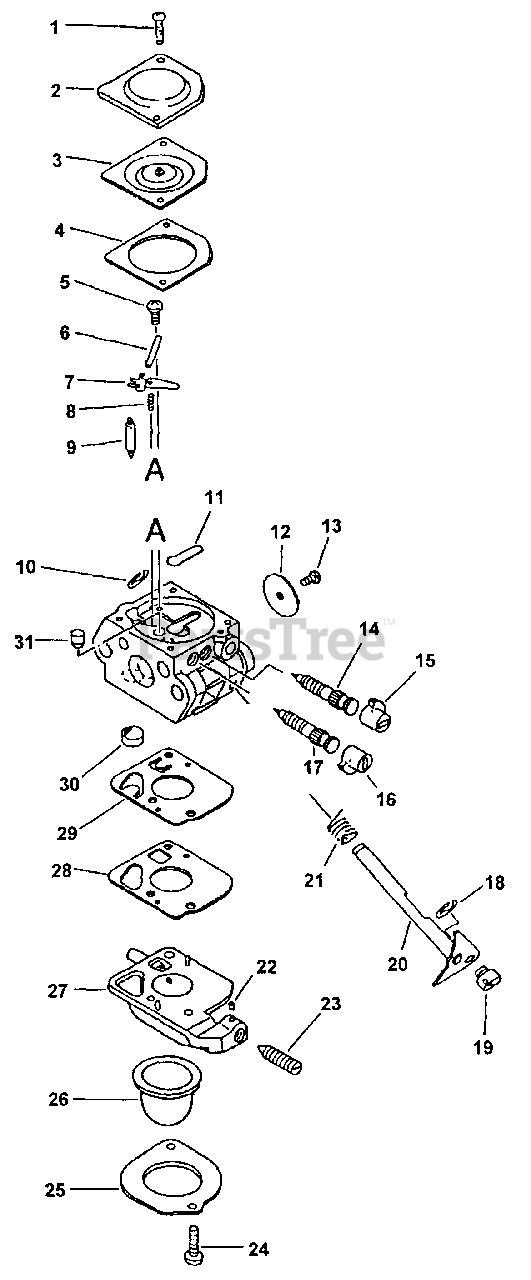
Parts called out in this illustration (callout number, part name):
2	COVER, METERING
3	DIAPHRAGM, METERING
4	GASKET, METERING
5	SCREW, METERING LEVER PIN
6	PIN, METERING LEVER
7	LEVER, METERING
8	SPRING, METERING LEVER
9	VALVE, NEEDLE
10	RING, RETAINING
11	PLUG, WELCH
12	VALVE, THROTTLE
14	NEEDLE - LOW SPEED
15	CAP, LIMITER
16	CAP, LIMITER
17	NEEDLE - HIGH SPEED
18	RING, RETAINING
20	SHAFT, THROTTLE
21	SPRING, RETURN
22	PIECE, FRICTION
23	SCREW, IDLE ADJUST
24	SCREW, RETAINER
25	RETAINER, PURGE BULB
26	BULB, PURGE
27	BASE, PURGE
28	GASKET, PURGE
29	DIAPHRAGM, PURGE
30	STRAINER
31	NOZZLE, CHECK VALVE
